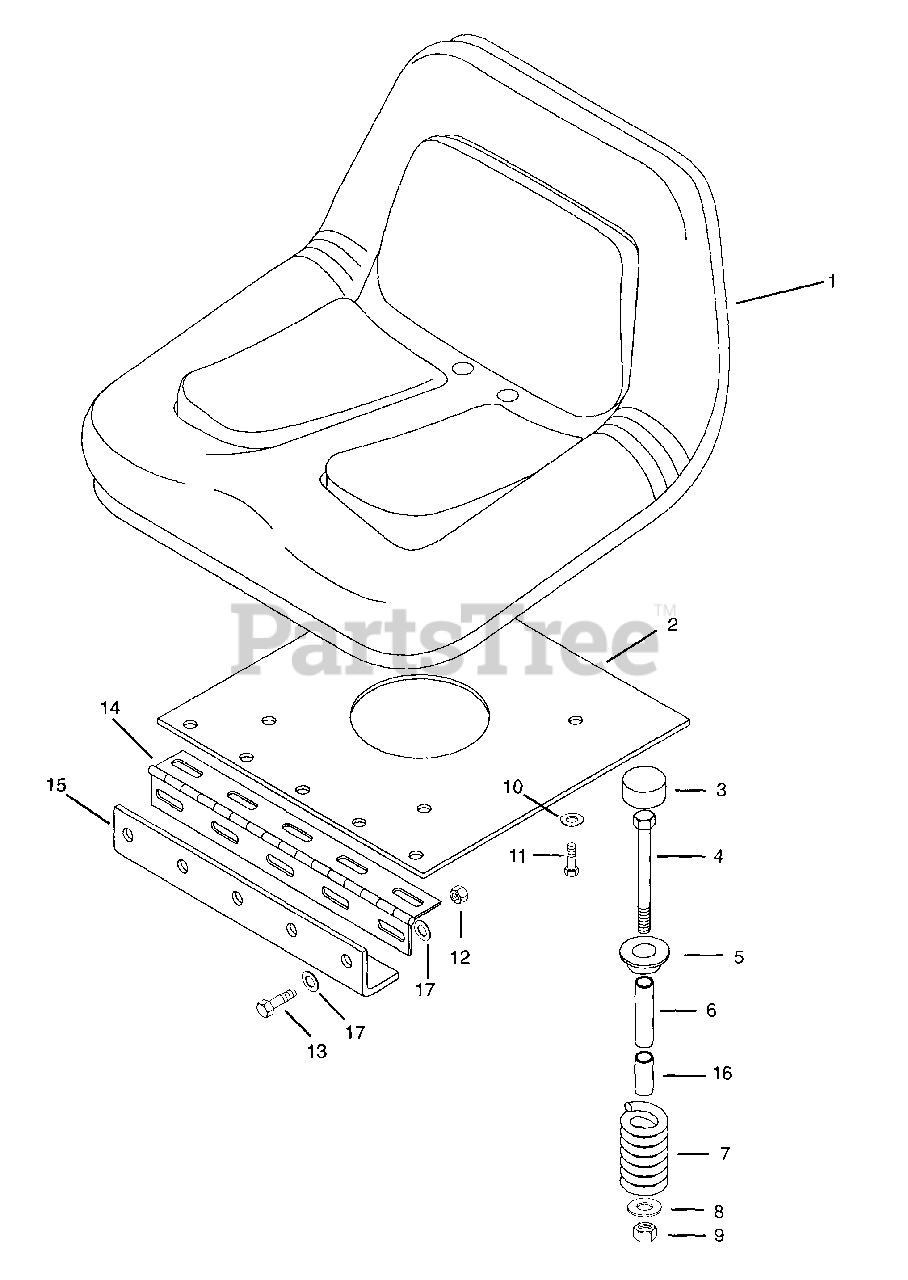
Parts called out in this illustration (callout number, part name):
1	Seat-V-560 High Back
2	Plate-Seat Mounting
3	Tip-Rubber
4	Bolt-Hex .25 - 20 x 2.25 Grade 5
5	Cap-Valve Spring
6	Bushing-Split Rolled
7	Spring-Compression .148 x 1.095 x 1.75
8	Washer-Flat-Steel .344 x .688 x .065
9	Nut-Locking-Center .25-20
10	Washer-Locking .31 x .078
11	Bolt-Hex .31-18
12	Nut-Locking-Center .31-18
13	Bolt-Hex .31-18 x .63 Grade 5
14	Hinge
15	Bracket-Seat Support
16	Bushing-Split Rolled
17	Washer-Flat-Steel .344 x .688 x .065
